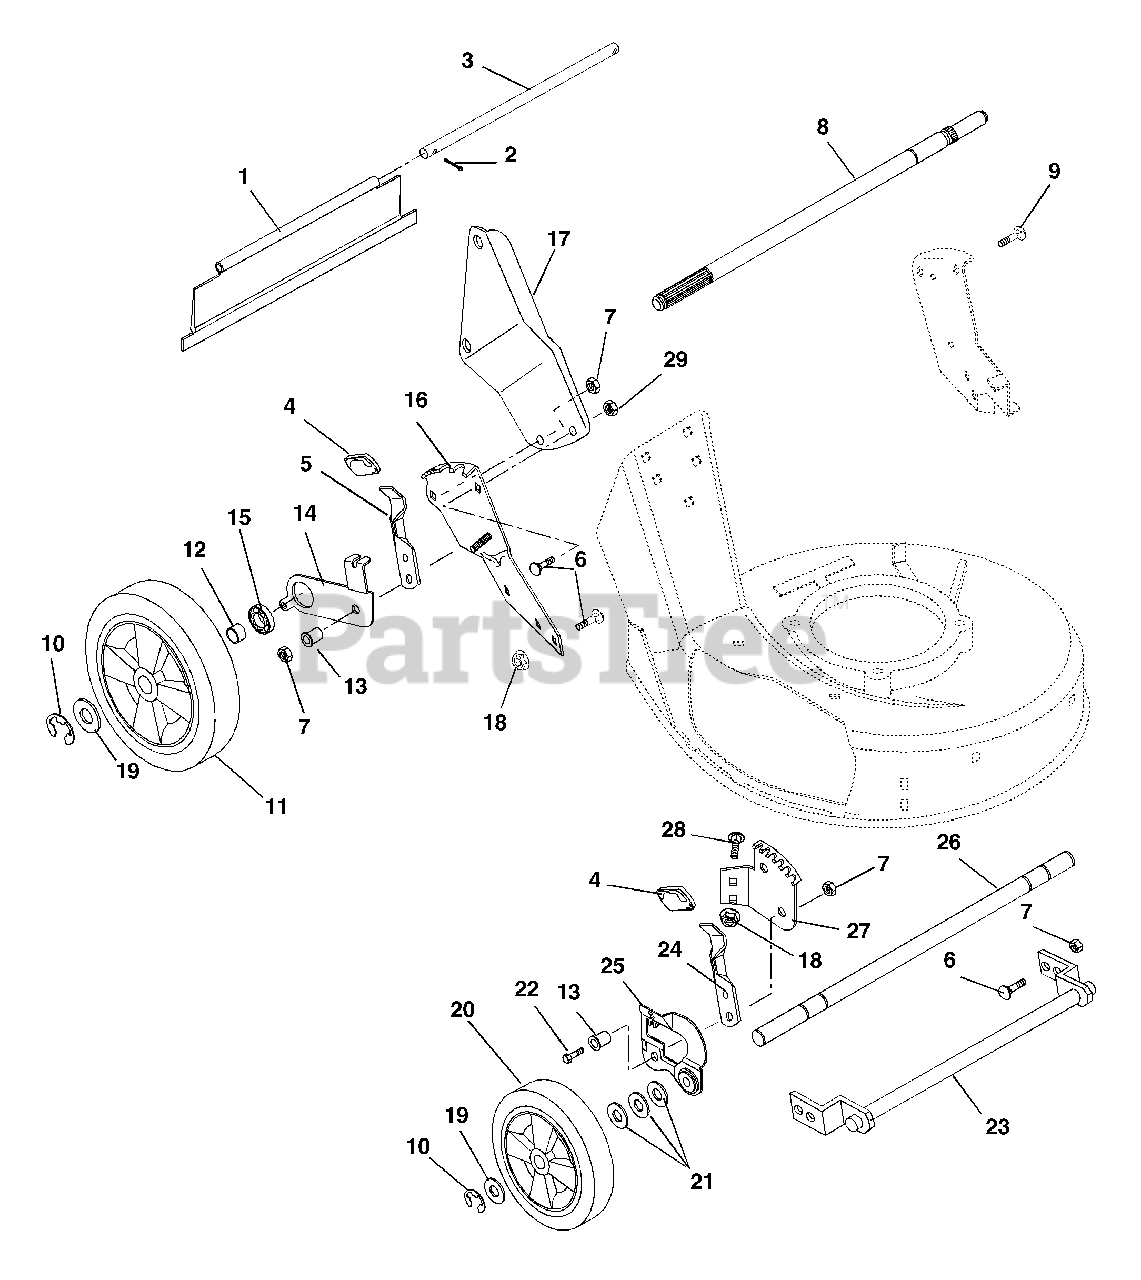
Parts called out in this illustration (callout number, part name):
1	Rear Protective Guard, Self Propelled
2	Pin-Cotter .06 x .50
3	Rod
5	Height Adjustment Lever
6	Bolt-Round Head Square Neck .31-18 x .62
7	Nut-Locking-Center .31-18
8	Rear Axle
9	Bolt-Round Head Square Short Neck .31-18 x 1.00
10	Ring-Retaining-External .500 x .042
11	Wheel, Left Hand Rear
11	Wheel, Right Hand Rear
11	Tire Skin 10 x 2.0
12	Spacer Tube
13	Bushing-Flange .312 x .500 x .344 x .880
14	Right Hand Rear Adjuster Bracket
14	Left Hand Rear Adjuster Bracket
15	Bearing-Ball .625 x 1.38 x .50
16	Rear Quadrant-Left Hand
16	Rear Quadrant-Right Hand
17	Bracket-Handlebar Mounting-Right Hand
17	Bracket-Handlebar Mounting-Left Hand
18	Nut-Locking-Flanged .31-18
19	Washer-Flat-Steel .505 x .880 x .072
20	Wheel-Front
21	Washer-Flat-Steel .520 x .827 x .062
22	Bolt-Hex .31-18 x 1.00 Grade 5
23	Dethatcher Retainer Weldment
24	Lever, Front Height Adjustment
25	Right Hand Adjuster Bracket
25	Left Hand Adjuster Bracket
26	Front Axle
27	Front Quadrant, Left Hand
27	Front Quadrant, Right Hand
28	Bolt-Round Head Square Neck .31-18 x .50 Grade 5
29	Nut-Locking-Nylon .31-18
